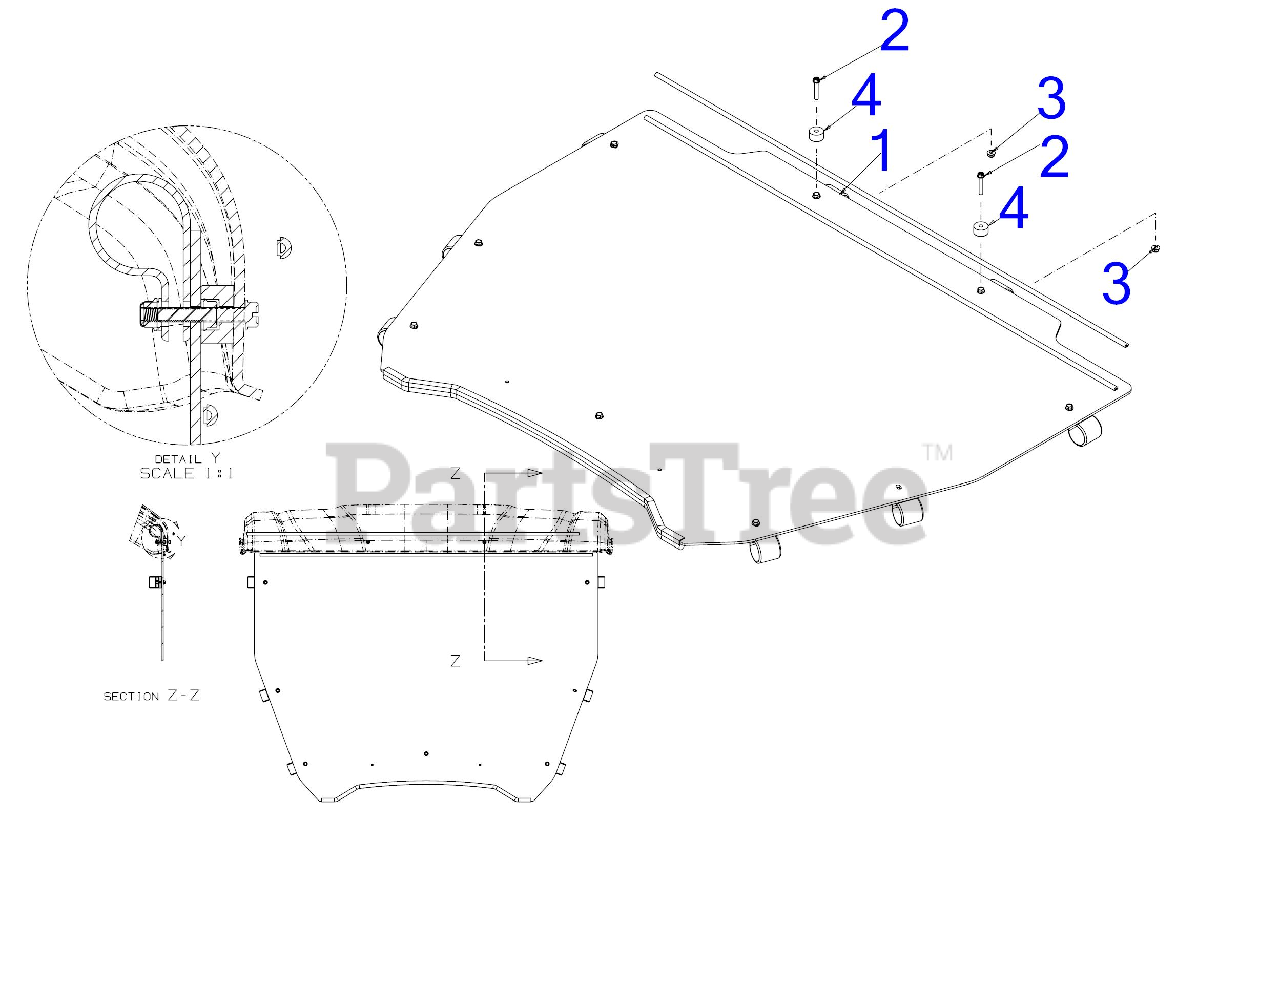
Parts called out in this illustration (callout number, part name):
1	WINDSHIELD
2	HEX FLANGE BOLT 1/4-20 X 1.5
3	FLANGE LOCK NUT
